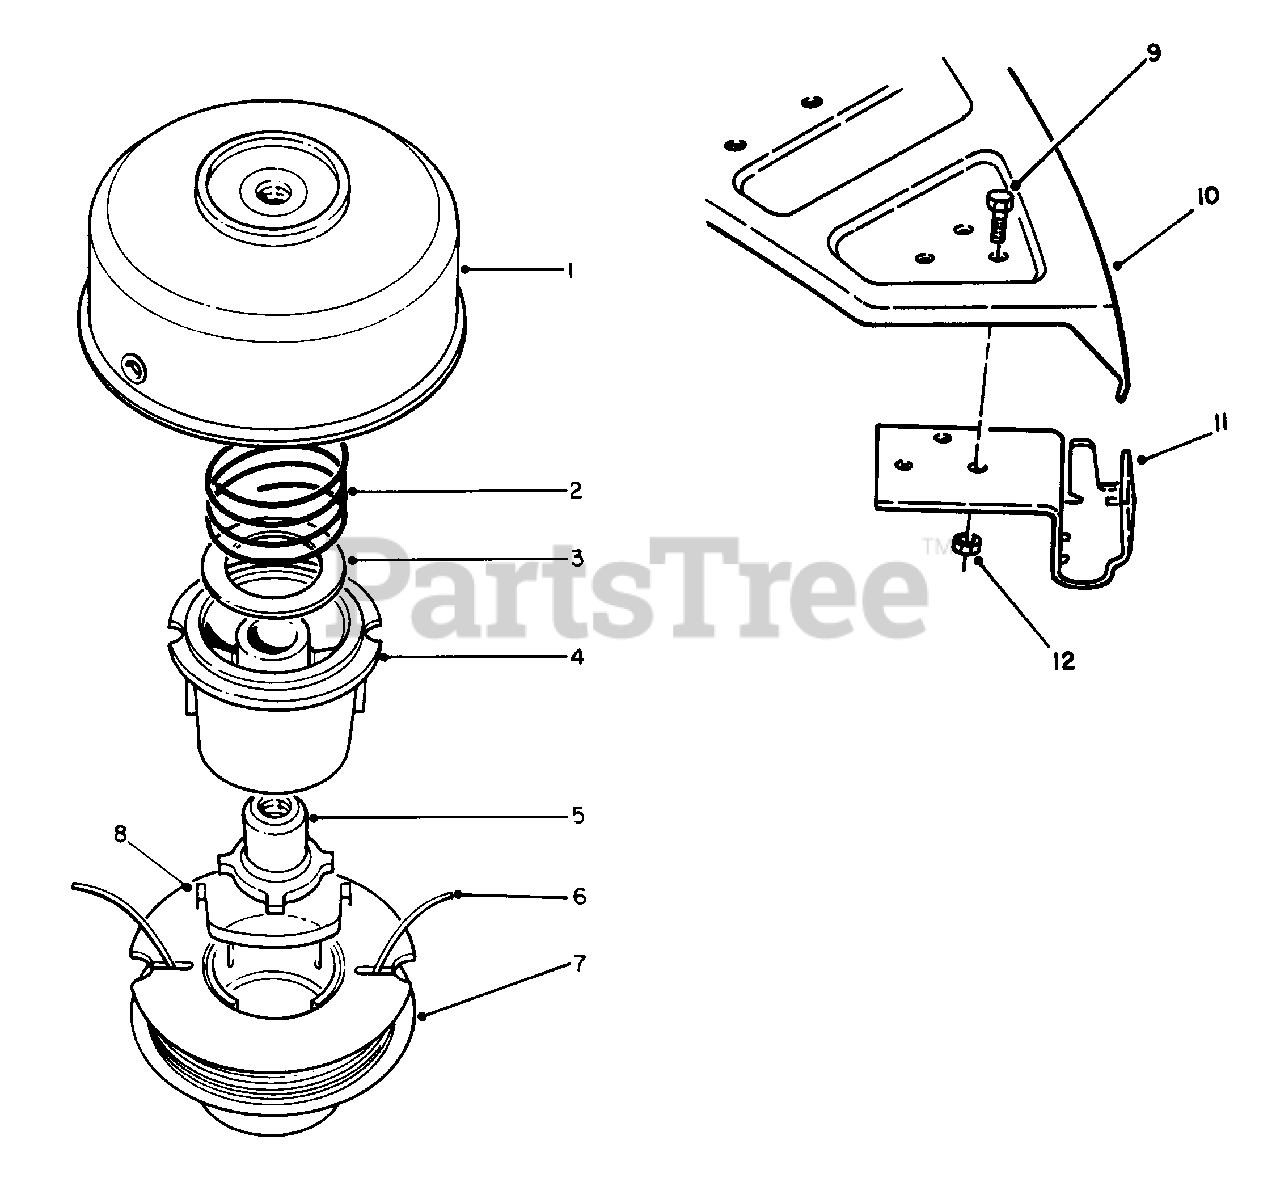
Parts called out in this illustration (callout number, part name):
1	Drum Assembly w/Eyelets
4	Spool Core
5	Driver L.H.
6	.080 Filament Line in Coil (38 Ft.)
7	Prewound Spool (Incl. Ref. #8)
8	Saddle-Spool Cap
9	Screw (Optional)
10	Shield-Grass (Optional)
11	Bracket & Knife Blade Assembly (Optional)
12	Lock Nut (Optional)
